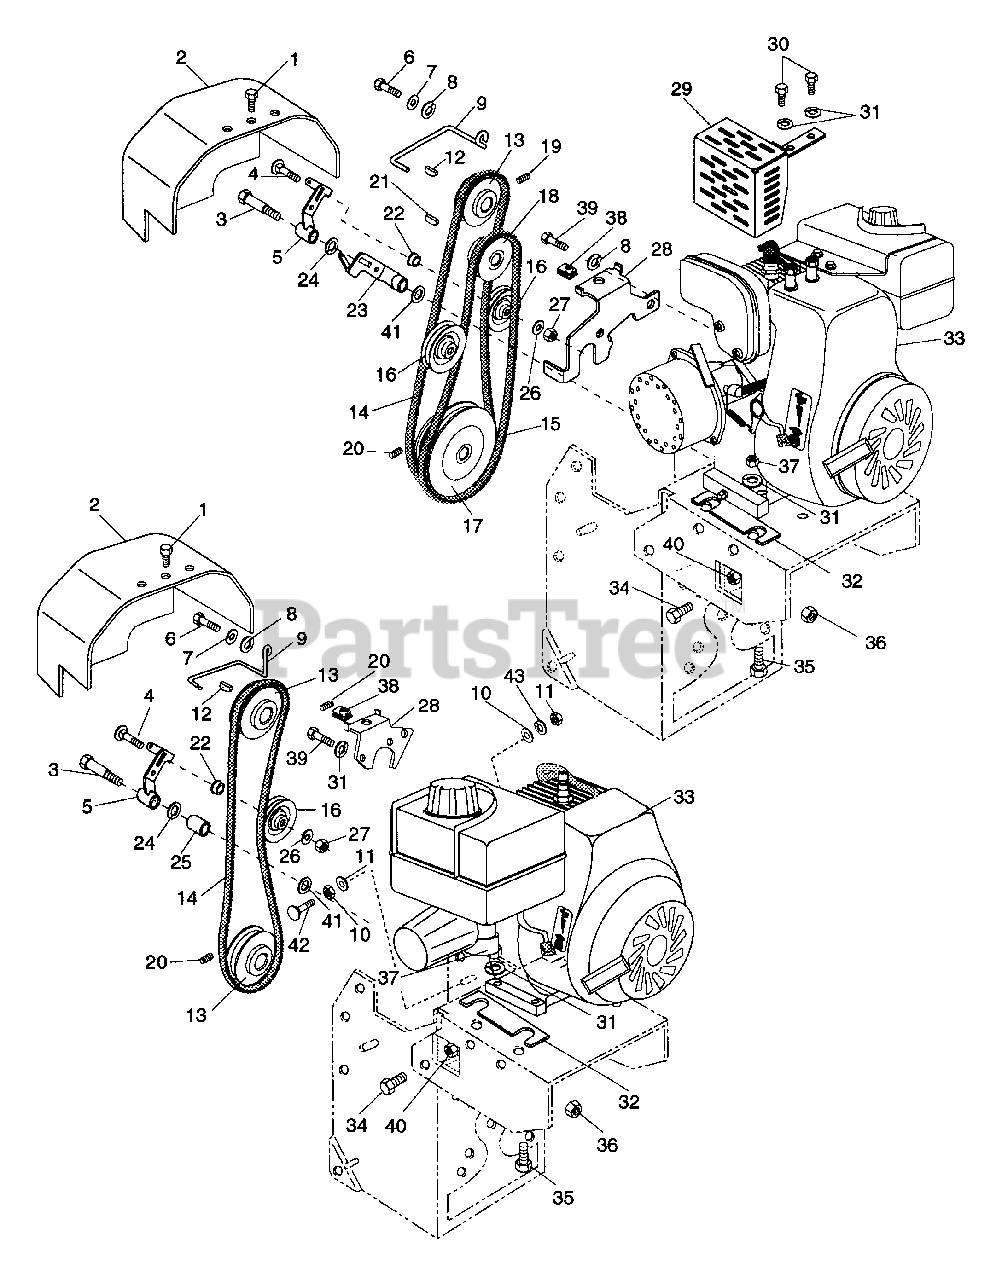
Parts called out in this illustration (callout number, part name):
1	BLT-HEX .25-20X.50 PL GR2
2	BELT COVER
3	WHEEL SHOULDER BOLT
4	BLT-RDHDSQNK .31-18X1.25 SHTPL
5	IDLER ARM FWD
5	CDLER ARM FWD
6	BLT-HEX .31-24X.75 PL GR5
7	WSHR-FL-STL.312X.734X.065PL
8	WSHR-LK .313X.062
9	BELT FINGER, TEC
9	BELT FINGER FWD TEC
9	BELT FINGER
10	NUT-HEX .375-16
11	WSHR-FL-STL .438X1.0X.083 PL
12	KEY-SQ .188X1.0X.188 SAE 8630
13	SHEAVE ASSEMBLY
13	SHEAVE 4.000X.751
14	V-BELT, 4L-WRAPPED
15	V-BELT, 3L-WRAPPED
16	IDLER
17	PLY-DBLV 5.50 X.75 W/KEY SALEM
18	REVERSE SHEAVE
19	SCR-SET .25-20X.38 SKHCUP OH
20	SCR-SET .32-18X.38 SKHCUPNL OH
21	KEY-WDRF .125X.625X.250 SAE5
22	SPCR, BRG .315X.50X.688X.281
23	IDLER ARM REV.
24	WSHR-FL-STL .520X.827X.062 YZ
25	SPACER .513X.748X1.062
26	WSHR-FL-STL .38X.875X.083 PL
27	NUT-LK .312-18 GR A PL
28	REVERSE BELT FINGER
28	BELT COVER BRACKET
29	MUFFLER GUARD
29	MUFFLER SHIELD
30	BLT-HEX .31-18X.63 PL GR 2
30	NUT-FLG. .312-18 PL
31	WSHR-LK .312X.097 PL HVY
32	SHIM
33	5 HP TILLER ENGINE- TEC
33	TECUMSEH 3HP TILLER ENG.
33	5 HP BRIGGS ENG 135292-0180-01
34	BLT-HEX .38-16X.75 PL GR5
35	BLT-HEX .31-18X1.75 PL GR2
36	NUT-LK-CTR .375-16 GR A PL
37	NUT-HEX .312-18
38	NUT-SPEED U-TYPE .250-20
39	BLT-HEX .31-24X.50 GR5
40	NUT-LK TOP .375-16 GR C YWZC
41	WSHR-FL-STL .531X1.062X.095 PL
42	BLT-RDHDSQNK .38-16X2.00 SHTYW
43	WSHR-LK .375X.115 HVY PL
